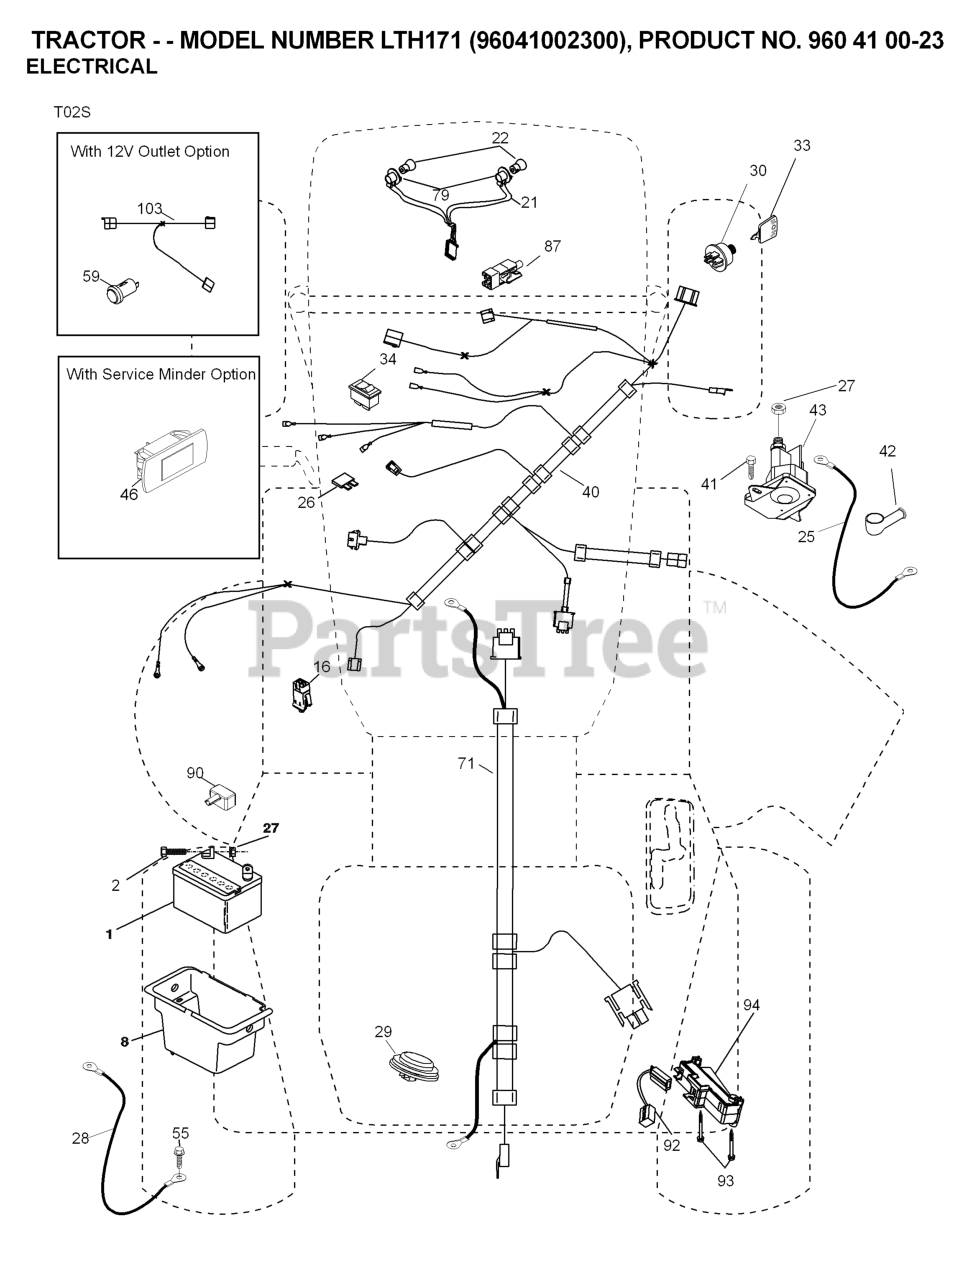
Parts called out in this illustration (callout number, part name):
1	BATTERY 12V .35 AMP
2	BOLT.HEX.1/4.X.3/4.DICHROMATE
8	BOX.BATTERY.MNT.REAR.L
16	SWITCH INTERLOOK PUSH-IN
21	HARNESS.LIGHT W/4152J BULBS
25	CABLE.STARTER.6GA.RED.
26	FUSE 20AMP
27	NUT
28	CABLE.BLACK.18"REAR.BA
29	SWITCH.SEAT.DELTA.OPC.
30	SWITCH.IGN.DELTA.W.LGH.ROS
33	KEY MLD GEN DELTA
40	HARNESS IGN. DASH
41	SCREW
42	TERMINAL COVER
43	SOLENOID.W/BRASS.PLUNGER
46	RP.GUAGE.SRVCMNDR.HRMTR.
55	SCREW 5/16"
71	HARNESS.IGN.CHASS.TEX.REAR.BAT
79	BULB HOLDER ASM.
87	SWITCH.INTRLCK.CLUTCH.
90	COVER, TERMINAL BATTERY
92	HARNESS.PIGTAIL.CONSLE
93	SCREW.PLASTITE
94	MODULE.REVERSE.ROS
